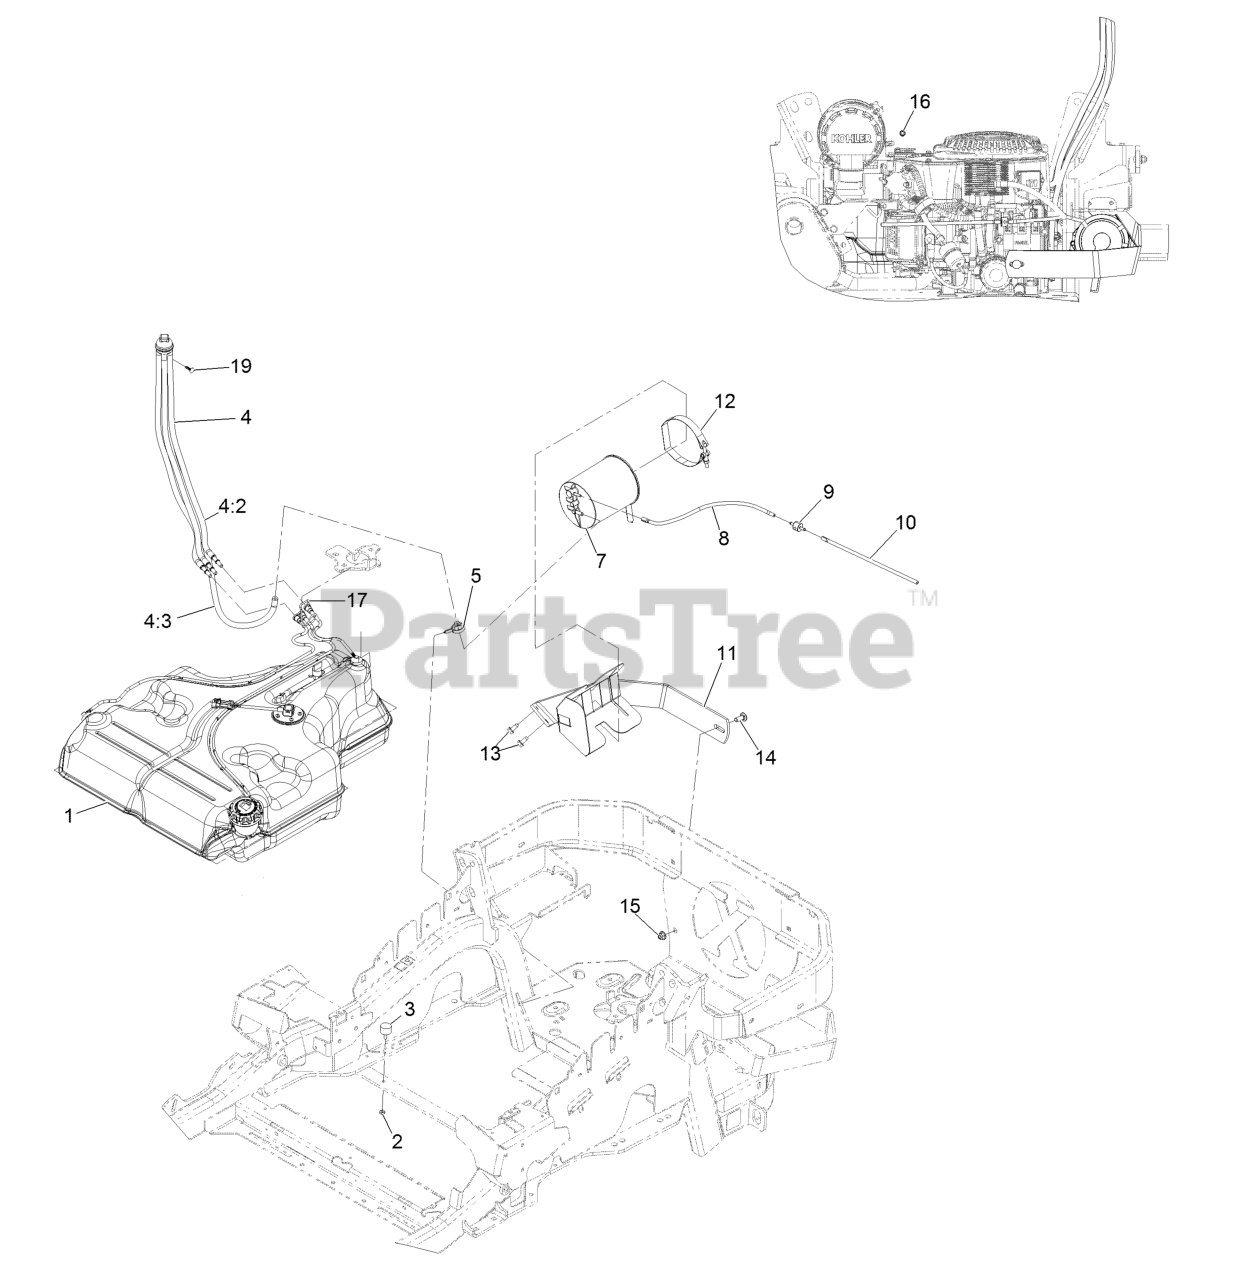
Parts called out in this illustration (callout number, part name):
1	Fuel Tank ASM
2	Nut-Jam 1/4-20
4	Fuel Manifold Vent ASM
4:2	Hose-Fuel Line 24"
4:3	Hose-Fuel
5	Clamp-Hose
7	Canister-Carbon, 1200Cc
8	Hose-Vent, Formed
9	Valve-Check, Vacuum
10	Hose-Vent, Formed
11	Mount-Canister
12	Clamp, T-Bolt
13	Screw-HWH 5/16-18 X 3/4 Tf
14	Bolt-Carriage 3/8-16 X 1
15	Nut-Nyloc 3/8-16 Flg
16	Plug-Port
17	Retainer-Line, Vapor
19	Plug-Plastic
